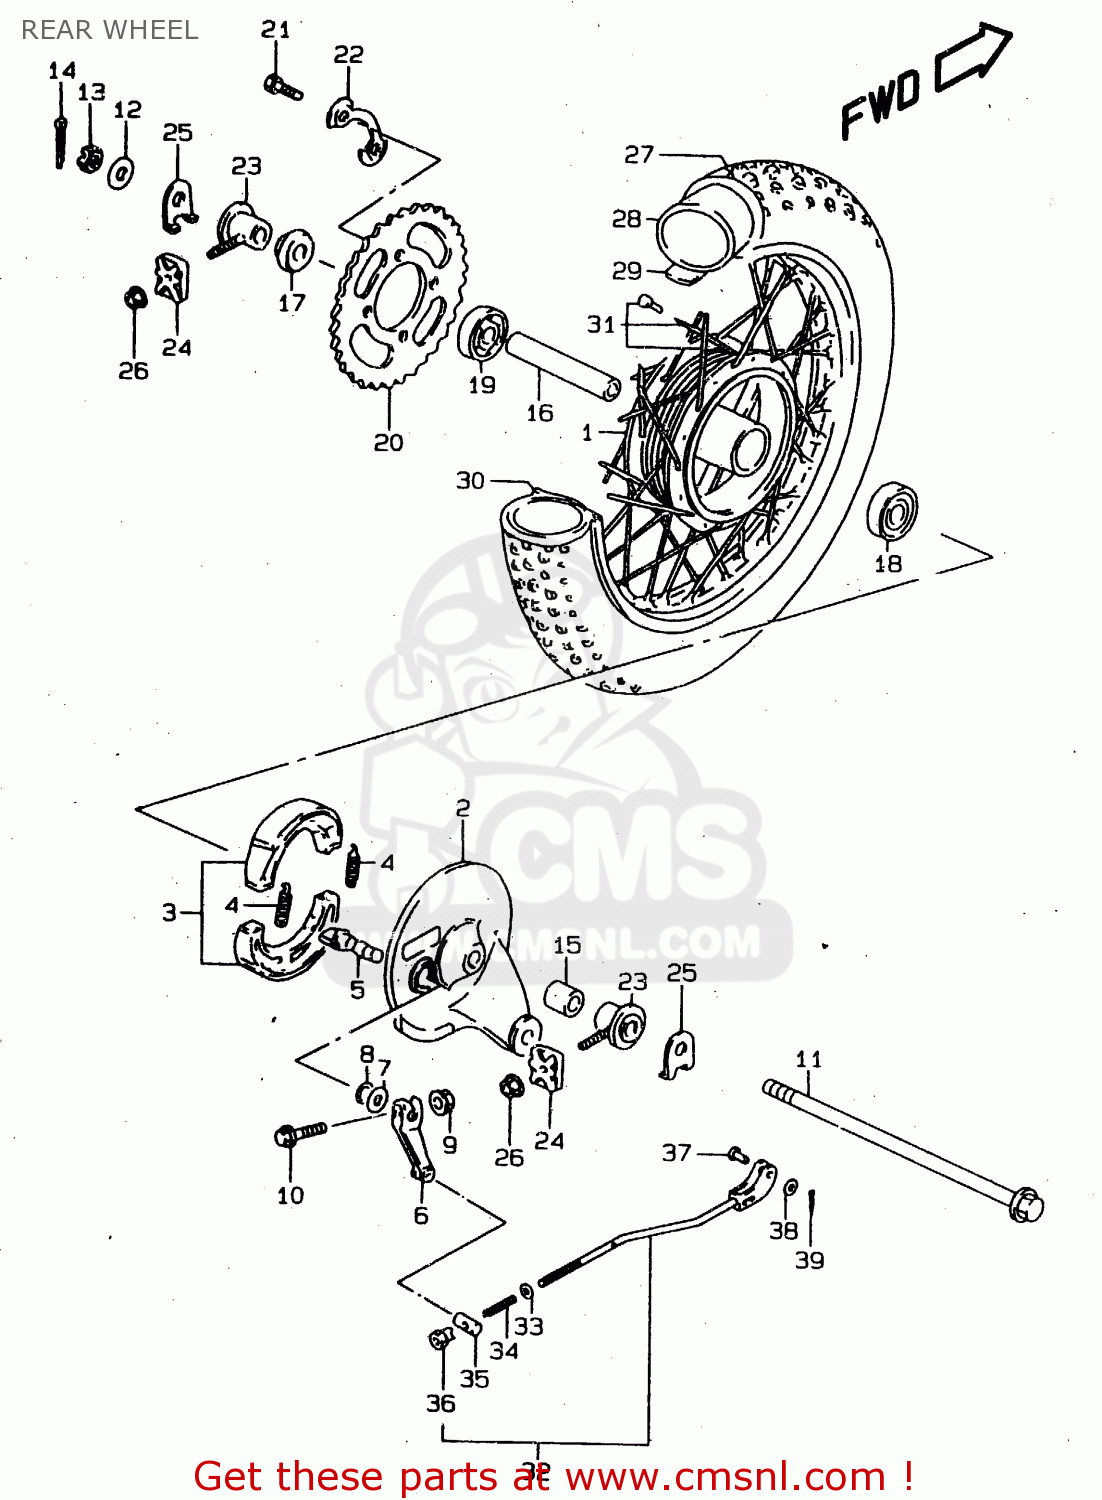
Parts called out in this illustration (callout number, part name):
1	HUB,RR
2	PANEL,RR BRAKE ANCHOR
3	SHOE SET,BRAKE (NAS)
4	SPRING(L:35.8)
5	CAM,BRAKE
6	LEVER,RR BRAKE CAM
7	WASHER(14.5X22X1.6)
8	O RING(D:2.5,ID:13.8)
9	NUT
10	BOLT
11	AXLE,RR
12	WASHER
13	NUT,M12X1.25X1
14	COTTER PIN
15	SPACER(12.1X22X22)
16	SPACER(12.6X19X91)
17	SPACER,RR AXLE,L
18	BEARING
19	BEARING
20	SPROCKET,RR(NT:34)
21	BOLT(8X25)
22	WASHER
23	ADJUSTER,CHAIN
24	PLATE,CHAIN ADJUSTER GUIDE
25	WASHER,CHAIN ADJUSTER
26	NUT
27	TIRE(3.00 12)
28	TUBE,INNER
29	PROTECTOR,INNER TUBE
30	RIM,RR WHEEL(1.60X12)
31	SPOKE ASSY,RR WHEEL
32	ROD ASSY,RR BRAKE
33	WASHER
34	SPRING
35	PIN(11X18)
36	NUT
37	PIN(L:13.5)
38	WASHER
39	PIN 20X20
